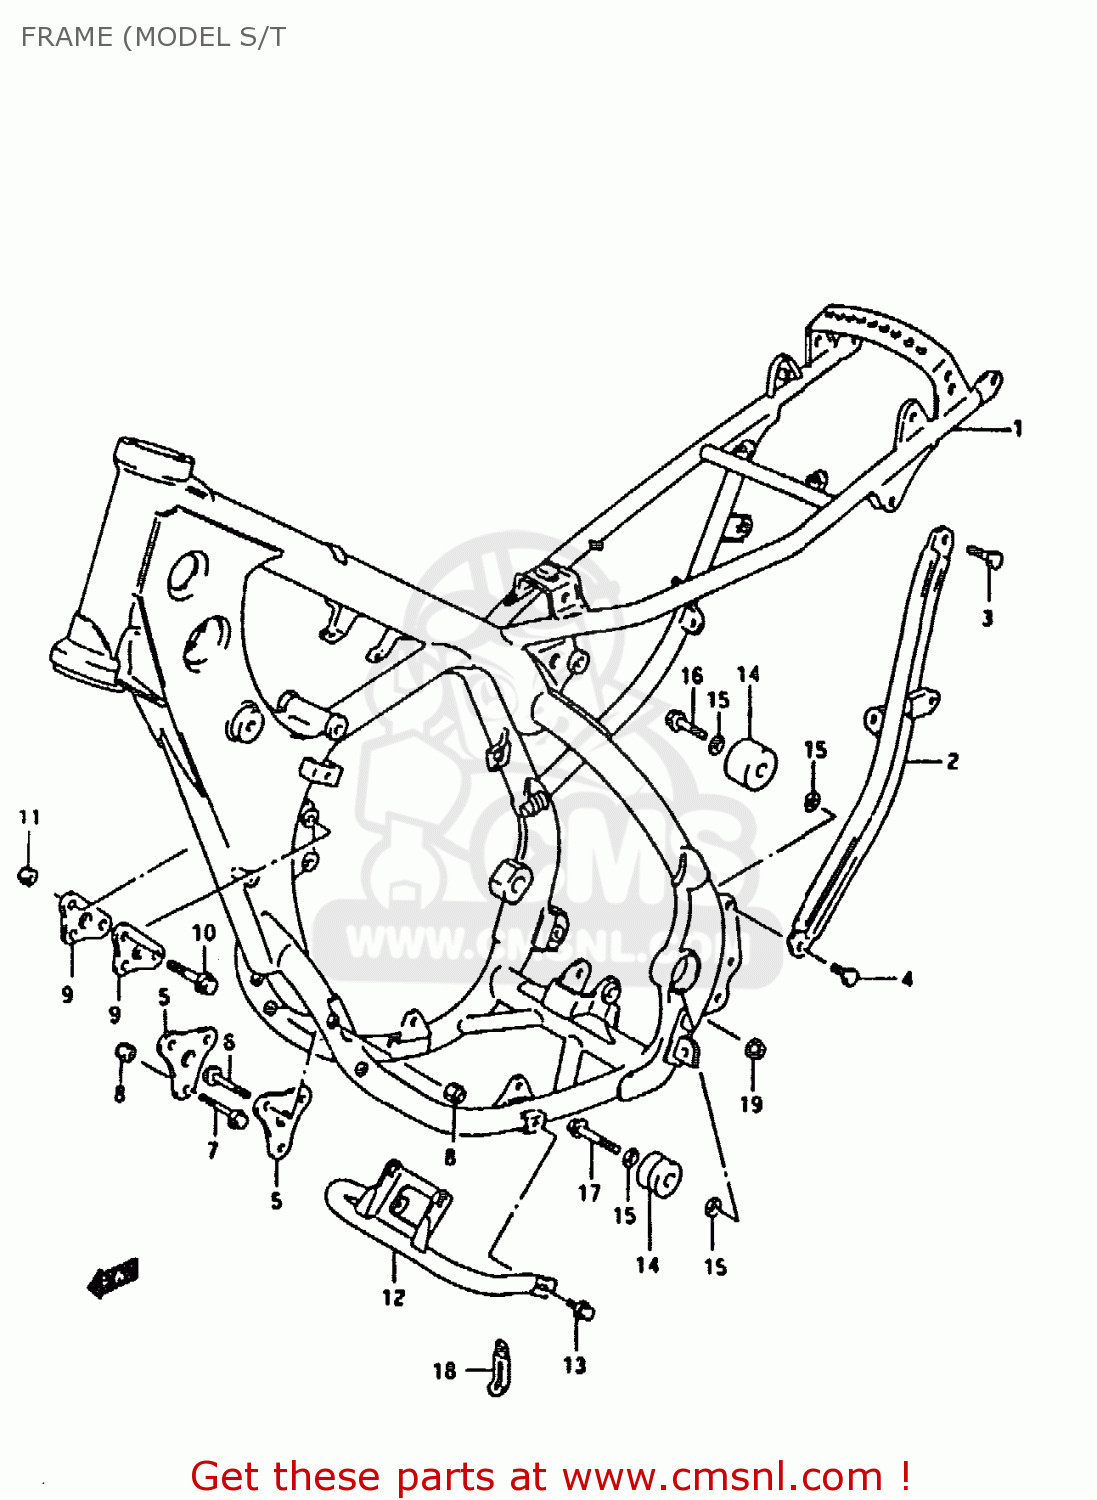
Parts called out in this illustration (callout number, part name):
1	FRAME COMP
2	TUBE,FRAME SIDE,L
3	BOLT
4	BOLT
5	PLATE,ENG MTG FR
6	BOLT 8X55
7	BOLT M8X65
8	NUT
9	PLATE,ENGINE MOUNT UPR
10	BOLT(8X45)
11	NUT
12	BOLT(8X45)
13	NUT
14	WASHER
15	PROTECTOR,ENGINE
16	BOLT
17	BOLT(8X45)
18	CLAMP(L:65)
19	NUT
20	SPACER(8.6X12X25.5)
21	ROLLER,CHAIN
22	WASHER
23	BOLT(8X41)
24	BOLT(8X45)
25	CLAMP
26	NUT
